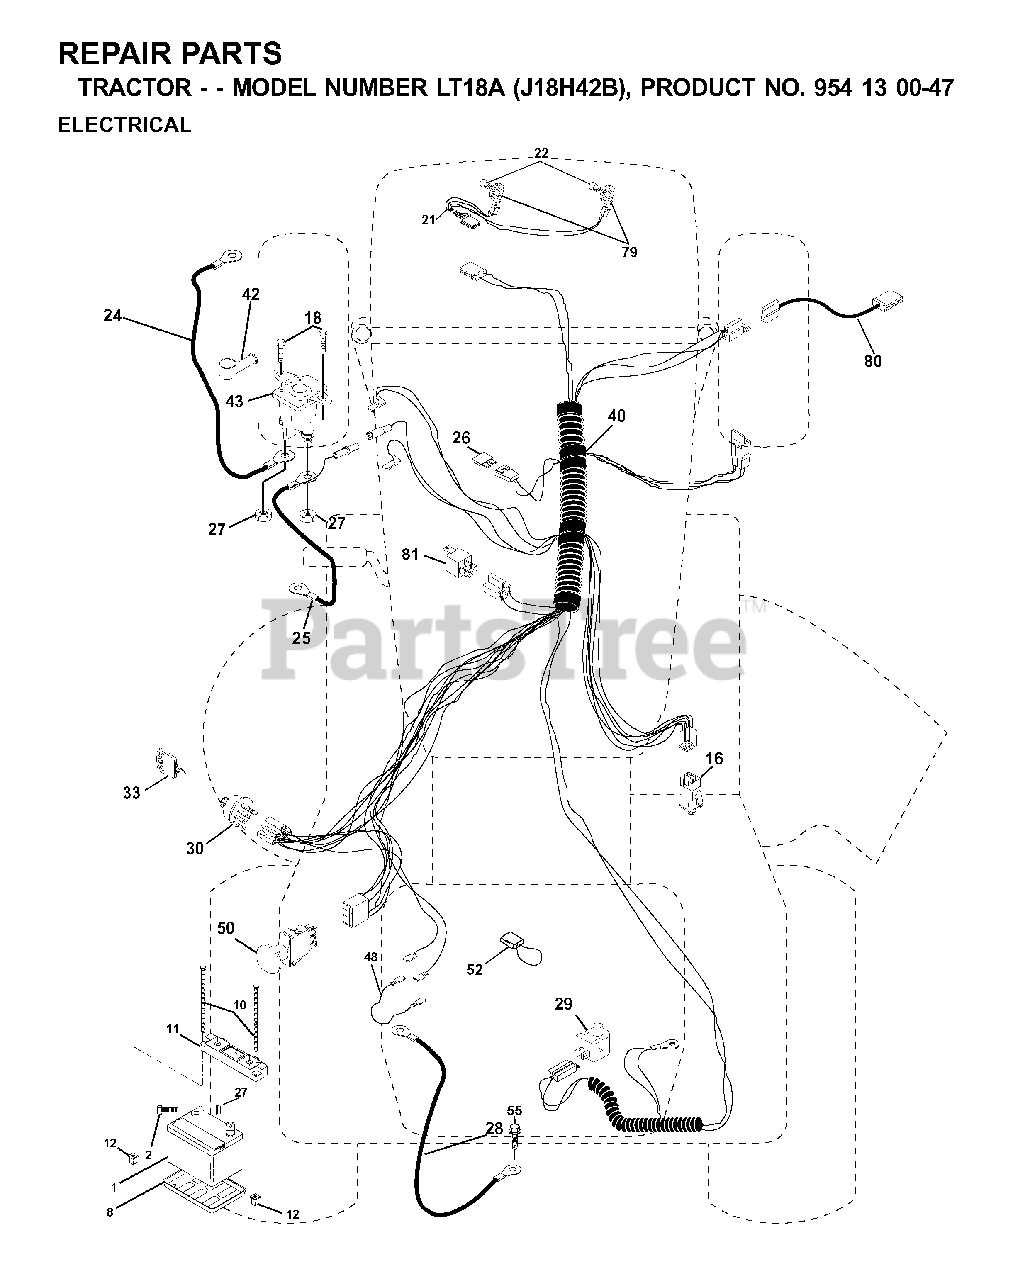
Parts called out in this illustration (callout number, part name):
1	REPL BY 532 12 38-99
8	BATTERY TRAY T
10	BOLT 1/4-20 X 7.5
11	BATTERY HOLDDOWN
12	NUT, PUSH NYLON 1/4" BATTERY
16	SWITCH INTERLOCK
18	SCREW
22	LIGHTBULB
25	CABLE BATTERY 6 GA 22" W/16W
26	FUSE 20AMP
27	NUT
28	CABLE GROUND 6 GA 21" 90T BLK
29	PLUNGER SWITCH (COLOR:OLIVE)
30	IGNITION SWITCH
33	KEY MLD GEN DELTA
42	TERMINAL COVER
43	REPL BY 532 1461-54
50	PTO SWITCH
52	WIRE PROTECTION LOOP
55	SCREW LT
80	HARNESS, CLUTCH
81	RELAY.ASSY.T
